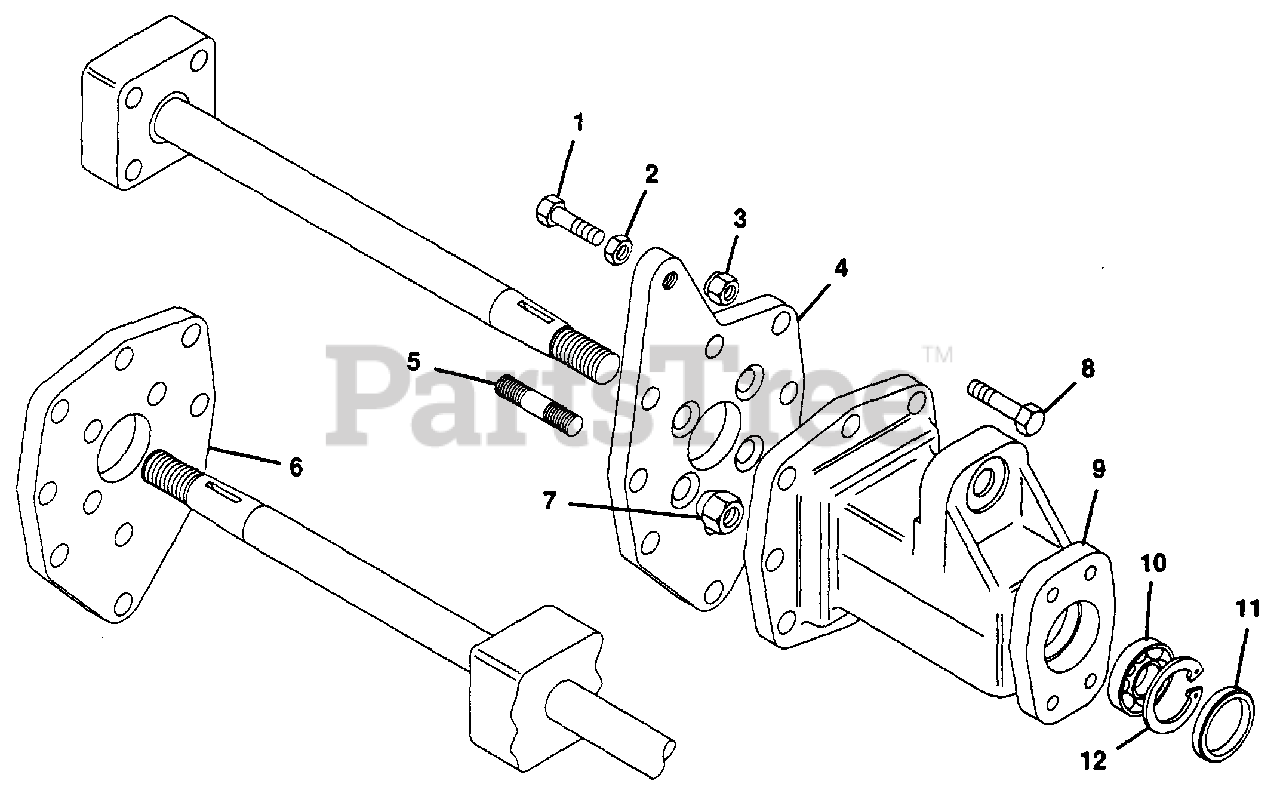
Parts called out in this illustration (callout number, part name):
1	Bolt, Hex 3/8-16x1.375
2	Nut, Jam 3/8-16
3	Nut, Lock 3/8-16
4	Plate, Axle L.H.
5	Stud, Axle
6	Plate, Axle R.H.
7	Nut, Rim
8	Bolt, Hex 3/8-16x1.625
9	Housing, Axle OFC
10	Bearing, Ball 1.250x2.250x.500
11	Seal, Oil Axle
12	Ring, Retaining
